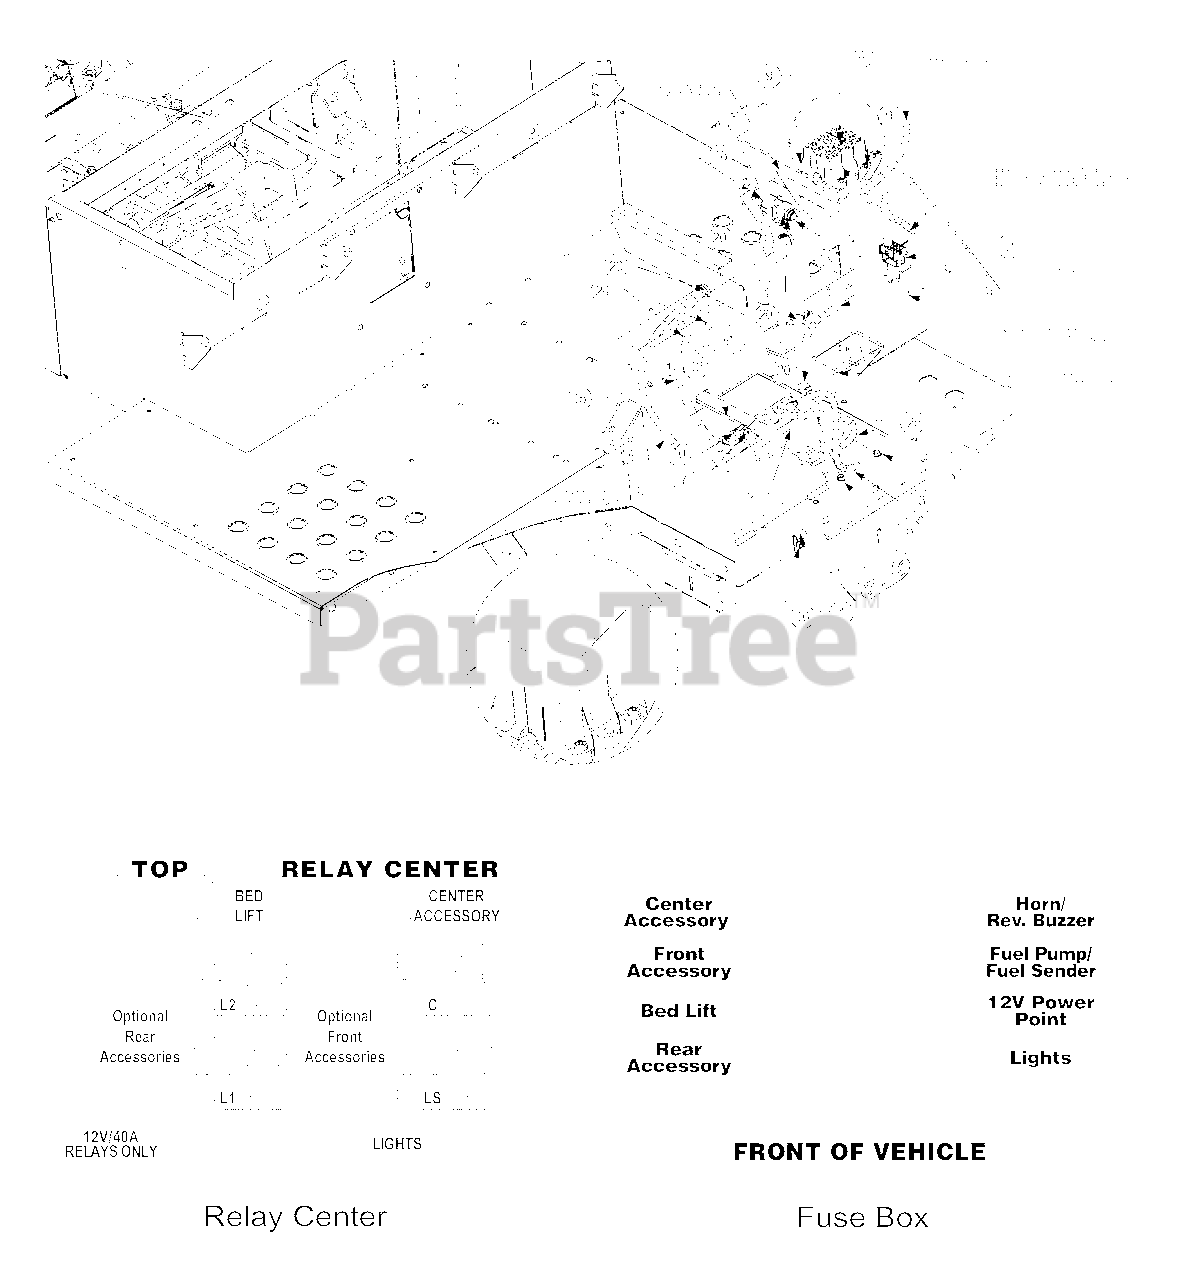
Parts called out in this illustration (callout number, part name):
1	Retainer Hook Bracket
2	Starter Harness Assembly
3	Motor Ground Harness Assembly
4	Screw, 1/4-20 x .50
5	Self-tapping Screw, 1/4-20 x 0.500
7	Hex Carriage Screw, 1/4-20 x.75
9	Screw, #10-24 x 0.75
10	Hex Sems Nut, 1/4-20
11	Protective Cover
12	Battery Strap
14	5 Amp Fuse
15	Utility Main Harness
16	Motor Harness
18	Switch
19	Battery
20	Cable Tie, .19 x 8.39 Tree Mount
24	Retainer Clip,.250 x.267
25	Conv. Conn. Assembly
